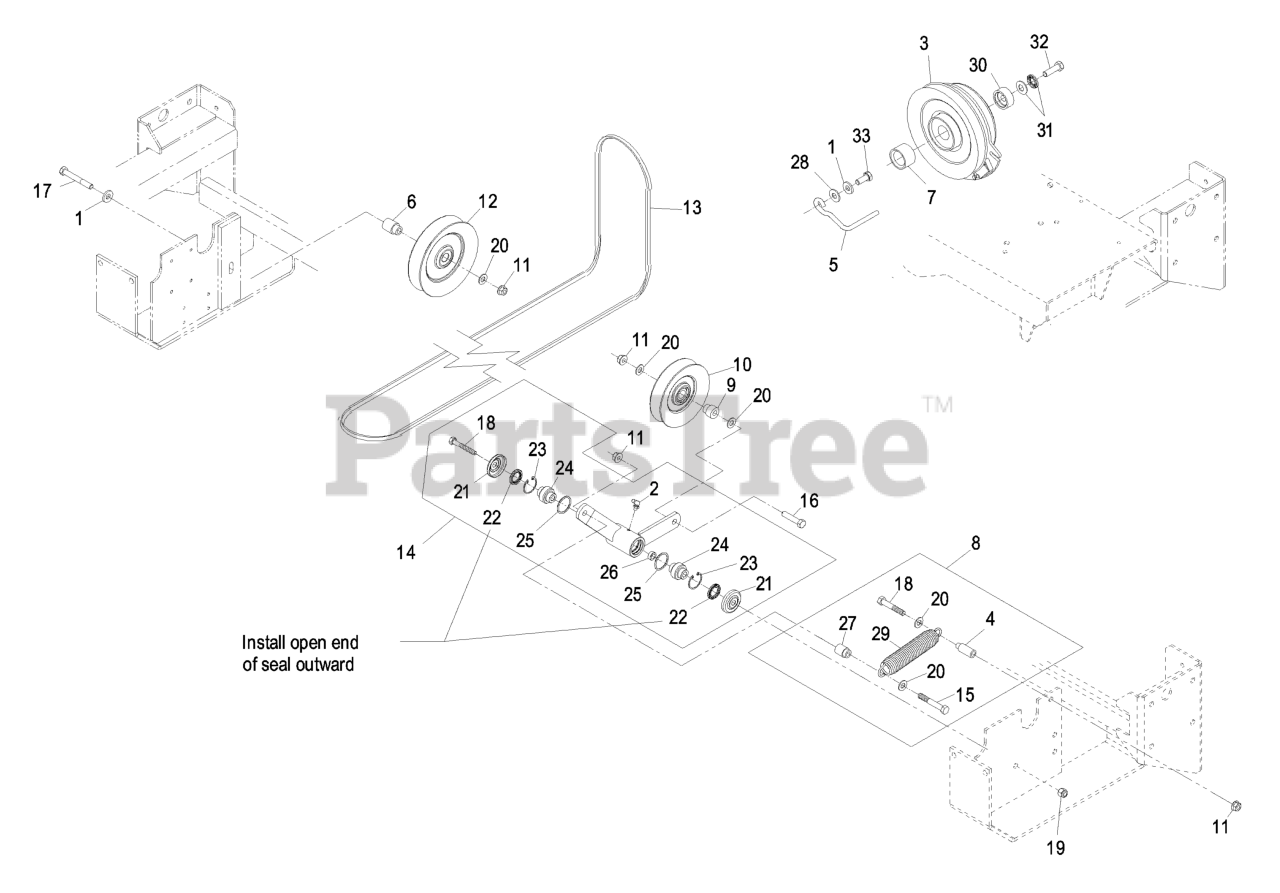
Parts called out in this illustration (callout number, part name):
1	WASHER-BELLEVILLE
2	FITTING-GREASE, 90 DEG
4	SPACER,SPRING MOUNT
5	ROD-BELT
6	BUSHING-IDLER
7	SPACER-CLUTCH
8	KIT,MULE DRIVE SPRING
9	BUSHING-IDLER
10	PULLEY-IDLER
11	NUT-HHF, WHIZ
12	PULLEY-IDLER
13	BELT-V B 118.75
14	KIT,MULE IDLER LZ
15	SCREW-HH
16	SCREW-HH
17	SCREW-HH
18	SCREW-HH
19	NUT-LOCK, NI
20	WASHER-FLAT
21	GUARD-TOP
22	SEAL-LIP, SINGLE
23	RING-SNAP
24	BEARING-SPHERICAL
27	BUSHING-IDLER
28	WASHER-FLAT
30	KEEPER-CLUTCH
31	WASHER-SPRING
32	SCREW-HH
33	SCREW-HH
